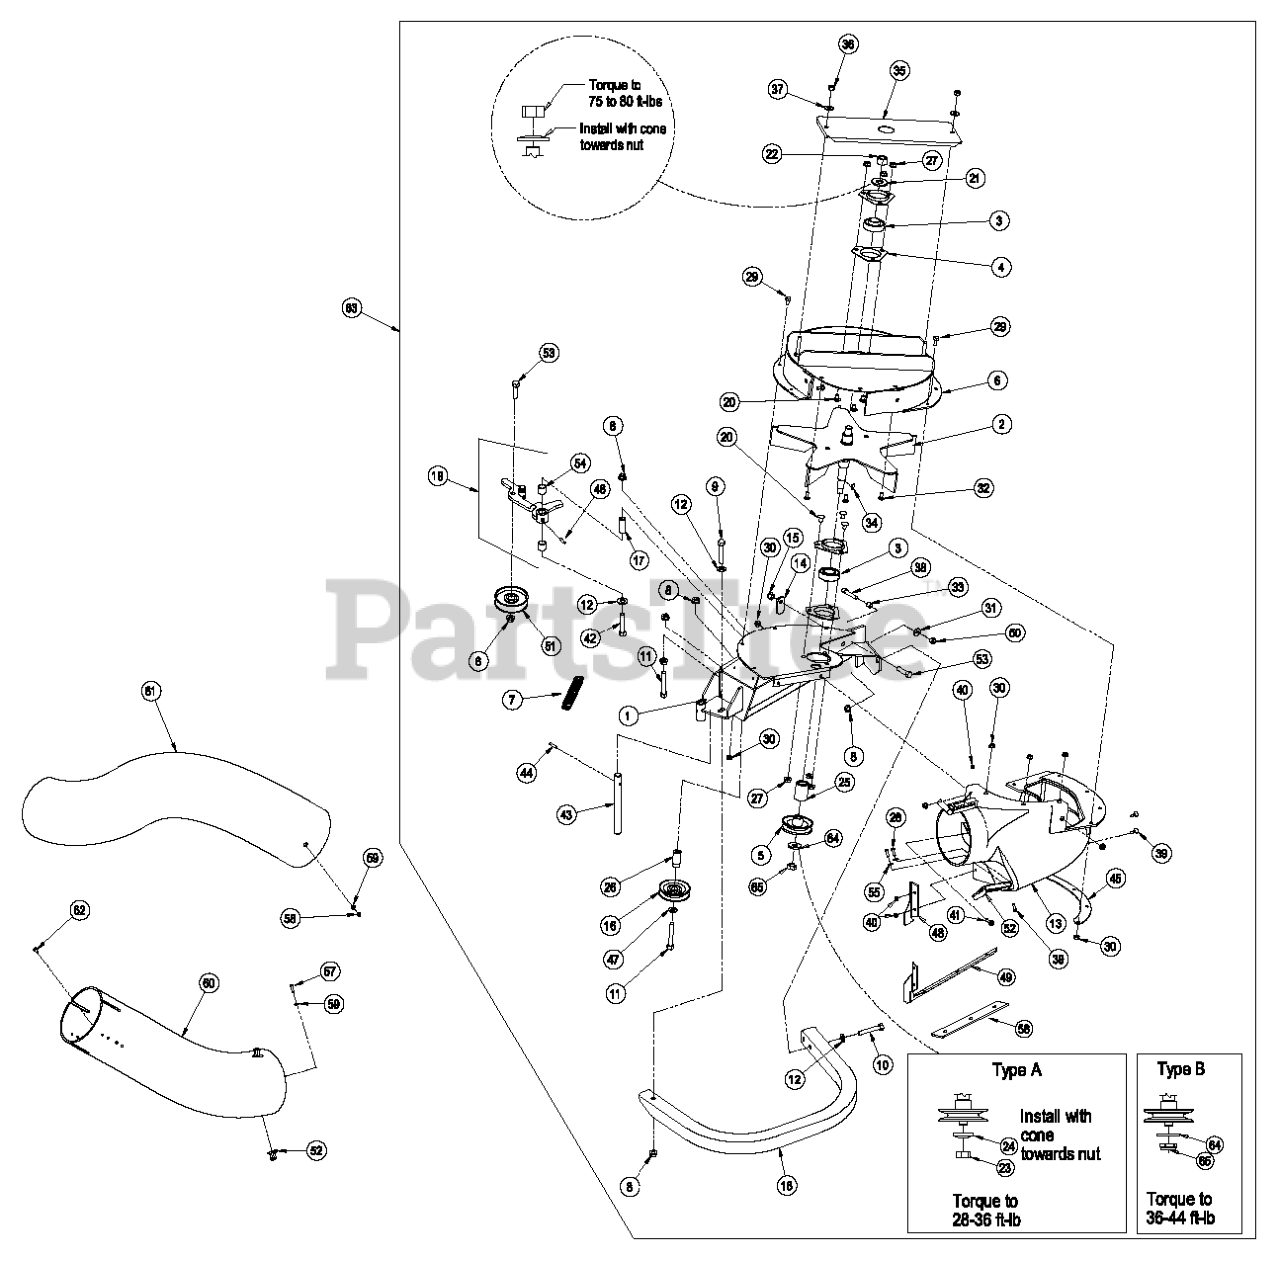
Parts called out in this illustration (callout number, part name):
1	WLD,BLOWER MOUNT
2	IMPELLER
3	BEARING
4	HOUSING-FLANGE
5	SHEAVE-BLOWER
6	ASM, UPPER HOUSING LZUV52
7	SPRING-IDLER
8	NUT-HHF, WHIZ
9	SCREW-HH
10	SCREW-HH
11	BOLT-CARR
12	WASHER-FLAT
13	CHUTE-BLOWER, SMALL
14	LATCH-CATCHER, GRASS
15	NUT-LOCK, NI
16	IDLER-INSIDE
17	BUSHING-PIVOT, IDLER
19	ASM, IDLER ARM - SERVICE
20	SCREW-CARR
21	WASHER-SPRING
22	NUT-HEX
23	NUT-JAM
24	WASHER-SPRING
28	SCREW-PPH
29	SCREW-HH
31	WASHER-SPRING
32	SCREW-CARR
33	BUSHING, LOCATOR
34	KEY-WOODRUFF
35	ASM, BEARING COVER
36	NUT-LOCK, NI
37	WASHER-FLAT
38	SCREW-HSH
39	SCREW-HEAD, TRUSS
42	SCREW-HSBH
43	SHAFT-CATCHER, GRASS
44	PIN-ROLL
45	PLATE-BACKING, BLOWER
46	FITTING-GREASE
47	WASHER-FLAT
48	PLATE, FILLER
49	PLATE, BLOCKER
50	NUT-HEX
51	IDLER-FLAT
52	LATCH DRAW
53	SCREW-HH
54	BUSHING
55	WASHER-FLAT
56	PLATE-REINFORCEMENT
57	SCREW-PPH
58	NUT-LOCK, NI
59	WASHER-FLAT
60	KIT,LOWER TUBE
61	TUBE-UPPER
62	SCREW-HWH
63	ASM, BLOWER LZUV52 - SERV
64	WASHER-FLAT
65	NUT-LOCK, NI
